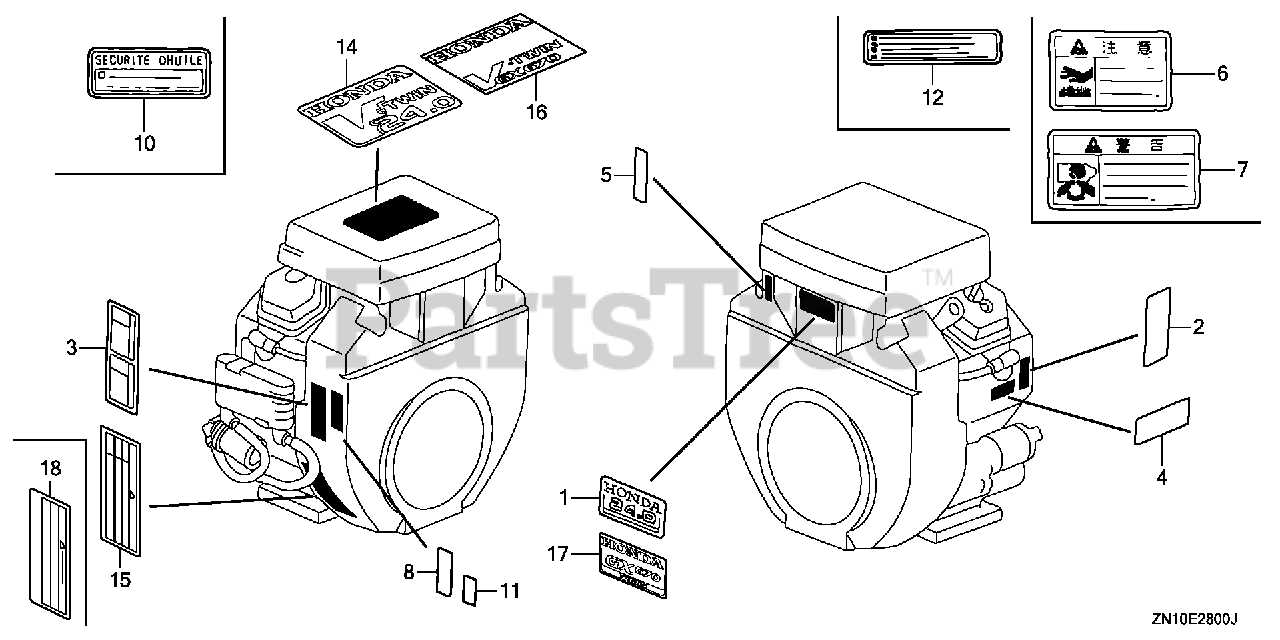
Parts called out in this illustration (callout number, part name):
4	MARK, OIL ALERT (ENGLISH)
11	LABEL, WARNING (NOT CERTIFIED FOR SALE)
18	MARK, OPERATOR CAUTION (ENGLISH)(MADE IN JAPAN)
